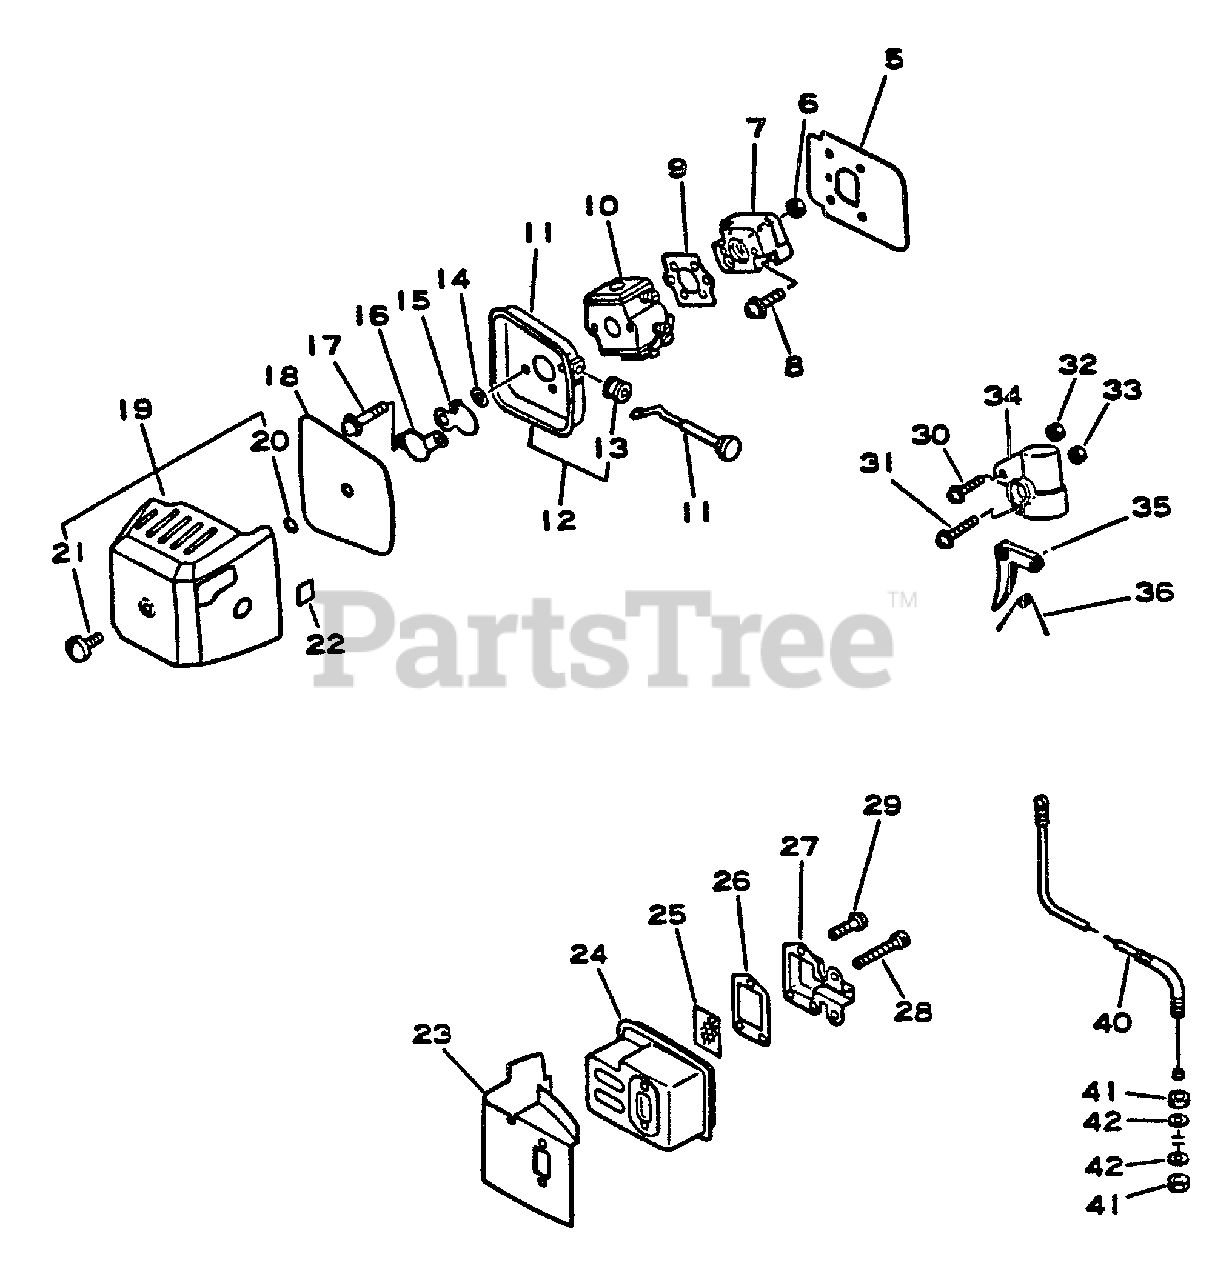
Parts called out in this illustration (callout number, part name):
5	HEAT SHIELD, INTAKE
6	NUT M5
7	INSULATOR, INTAKE
8	SCREW 5×20
9	GASKET, INTAKE
10	CARBURETOR - C1U-K10
11	ROD, CHOKE
12	CASE, AIR FILTER
13	GROMMET, CHOKE
14	WASHER 5.2×8×0.8T
15	SHUTTER, CHOKE
16	CASE, AIR FILTER
17	SCREW 5×57
18	FILTER, AIR
19	COVER ASSY, AIR FILTER
22	LABEL - CHOKE
23	COVER, MUFFLER
25	SCREEN, SPARK ARRESTER
26	GASKET, EXHAUST
27	GUIDE, EXHAUST
28	BOLT M5×50
29	SCREW 4×10
30	SCREW 5×28
32	NUT M5
33	LOCKNUT - 5
34	BRACKET, TRIGGER
35	TRIGGER, THROTTLE
40	CABLE, THROTTLE
